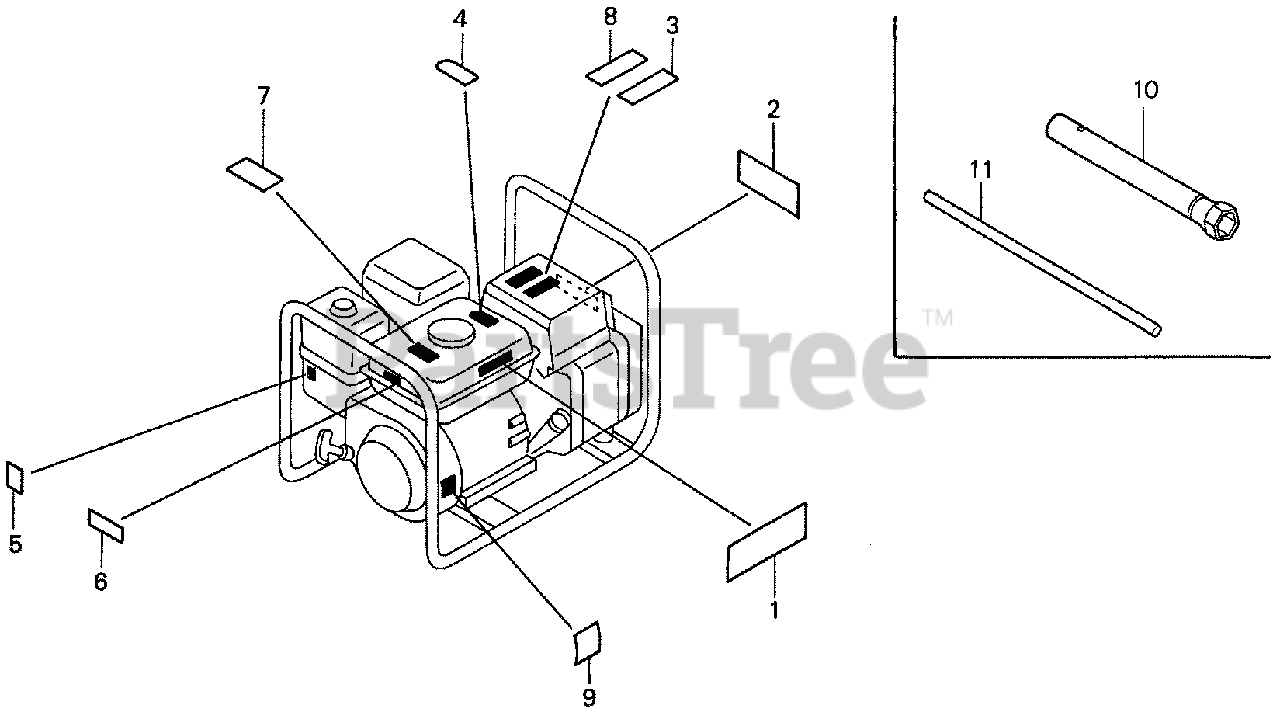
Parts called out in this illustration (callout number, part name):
1	MARK, EMBLEM (EZ2500)
1	EMBLEM (EZ2500)
2	PLATE A, CAUTION (EZ2500)
3	LABEL, RAIN WARNING (ENGLISH)
4	MARK, CAUTION (ENGLISH/FRENCH)(SPANISH)
5	MARK, CHOKE
6	MARK, OIL ALERT (E)
7	MARK, CAUTION (CO)(ENGLISH/FRENCH)(SPANISH)
8	LABEL, CONNECT WARNING (ENGLISH)
9	MARK, OIL CAUTION
10	WRENCH, SPARK PLUG
11	BAR A, HANDLE
